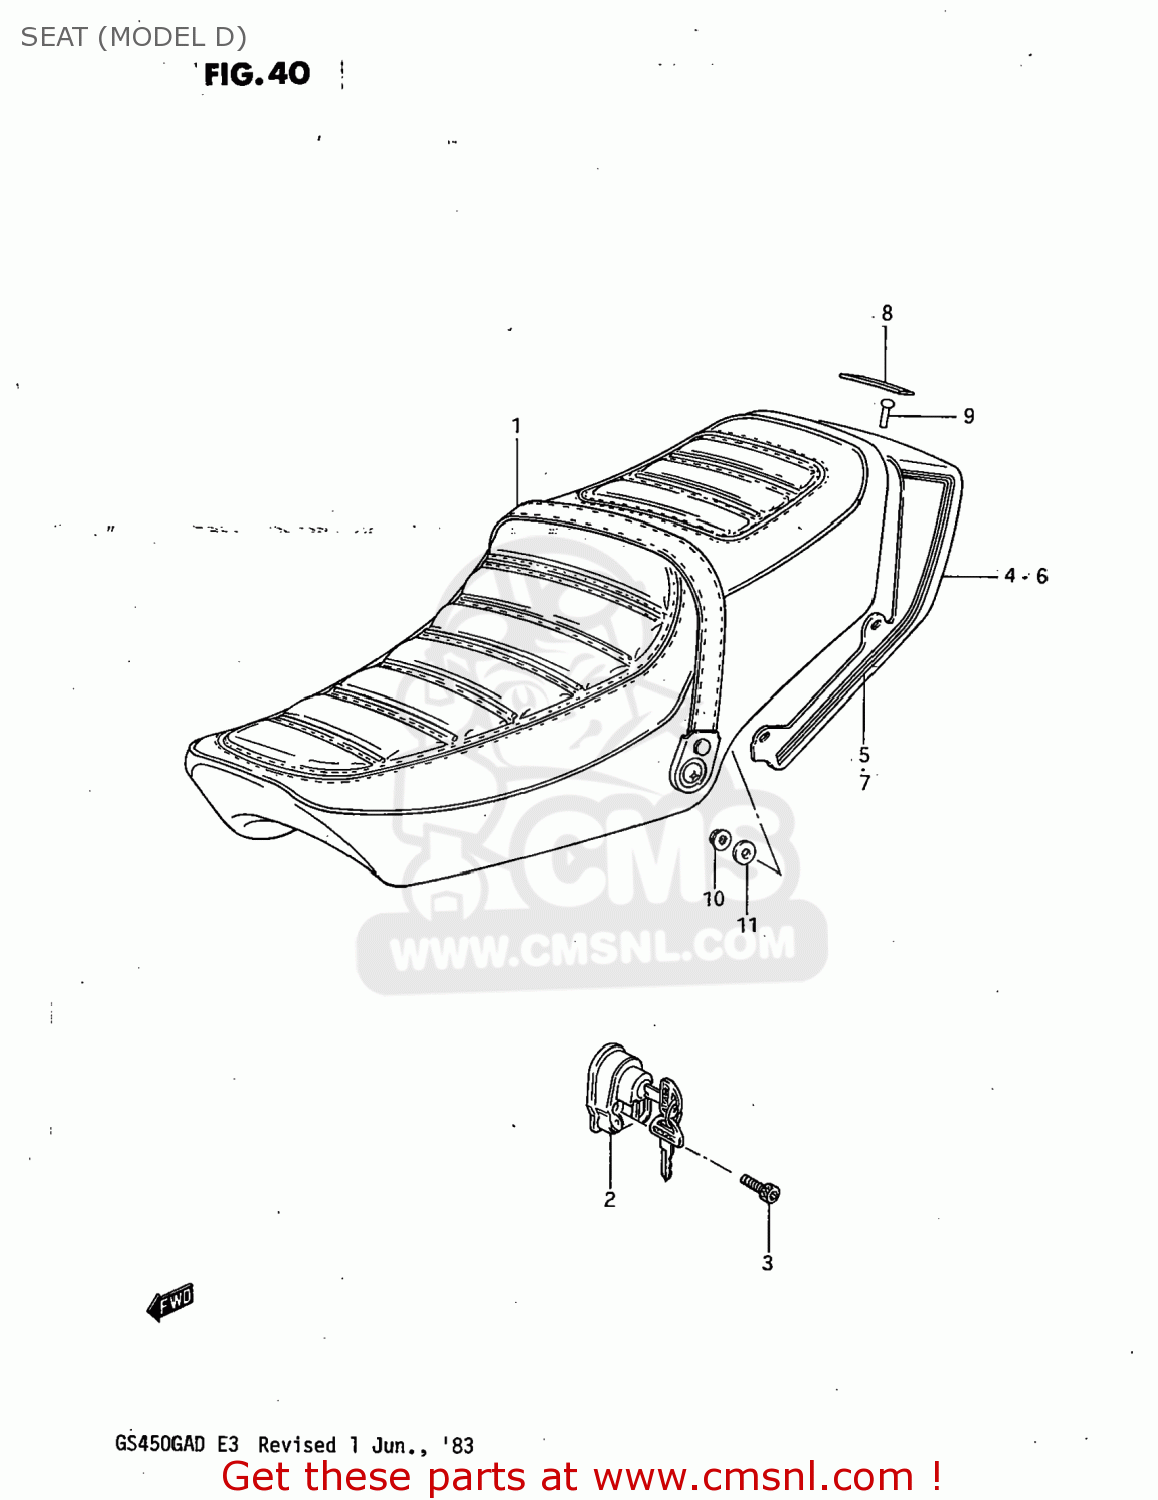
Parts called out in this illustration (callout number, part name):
1	SEAT ASSEMBLY
2	LOCK ASSY,HELMET
3	BOLT 5X25
4	COVER,SEAT TAIL
5	TAPE SET,SEAT TAIL COVER
6	COVER,SEAT TAIL
7	TAPE SET,SEAT TAIL COVER
8	EMBLEM
9	RIVET
10	NUT
11	WASHER (6.7X16X1.8)
